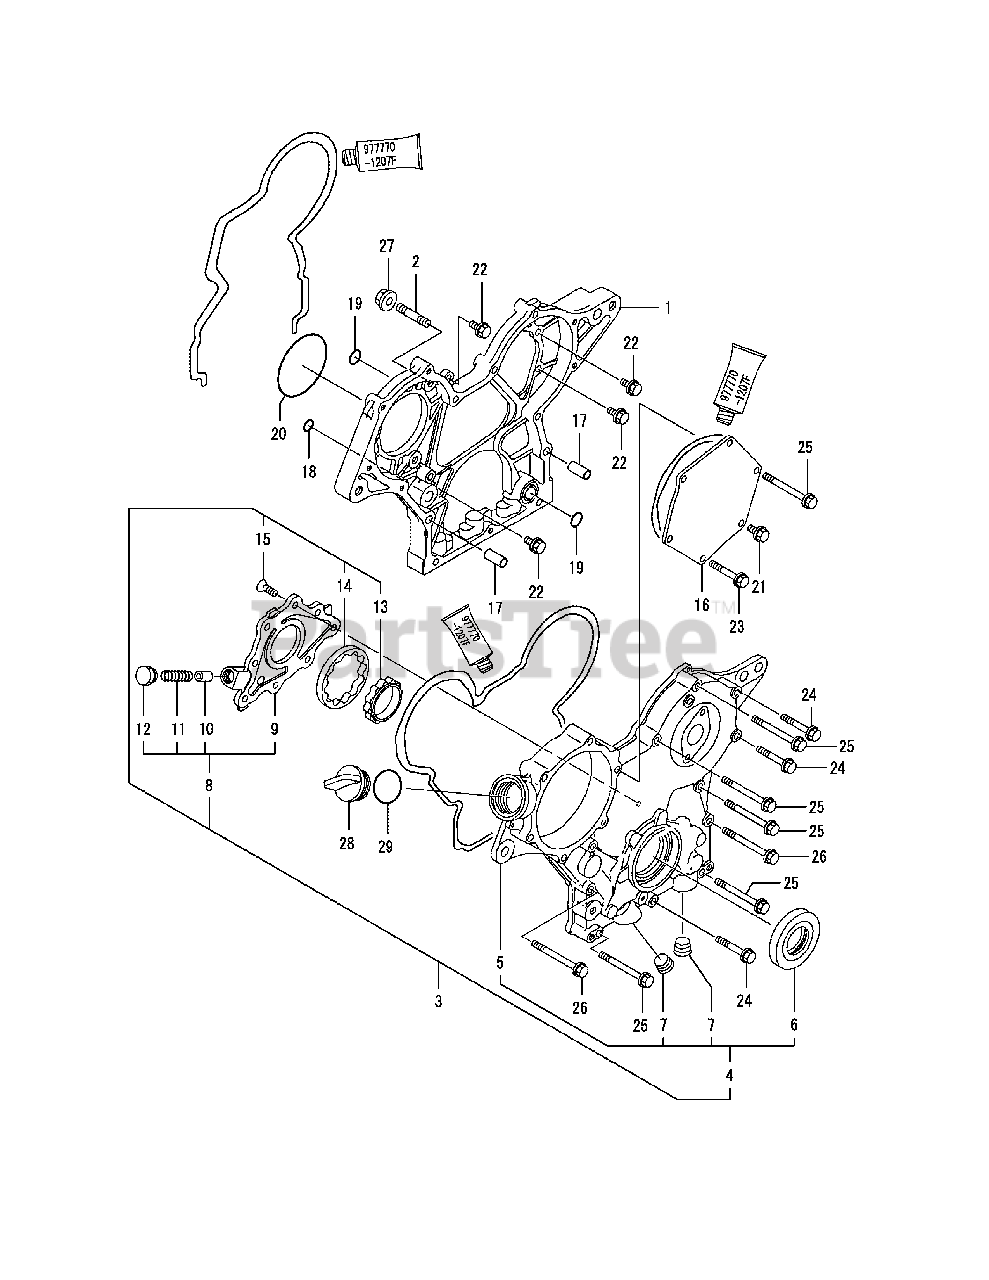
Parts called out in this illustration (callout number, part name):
3	Cover Assembly, Gear Case
4	Cover Assembly, Gear Case
5	Cover, Gear Case
7	Plug Pt, 3/8, Screw
8	Cover Assembly, Pump
9	Cover, Lub. Oil Pump
15	Screw, M6 x 16
16	Cover, Pump Timing
20	O-Ring, F.I. Pump
21	Bolt M 6 x 12 Plated
22	Bolt M 6 x 16 Plated
23	Bolt M 6 x 40 Plated
24	Bolt M 6 x 40 Plated
25	Bolt M 6 x 60 Plated
26	Bolt M 6 x 65 Plated
29	O-Ring 1A P-32.0
